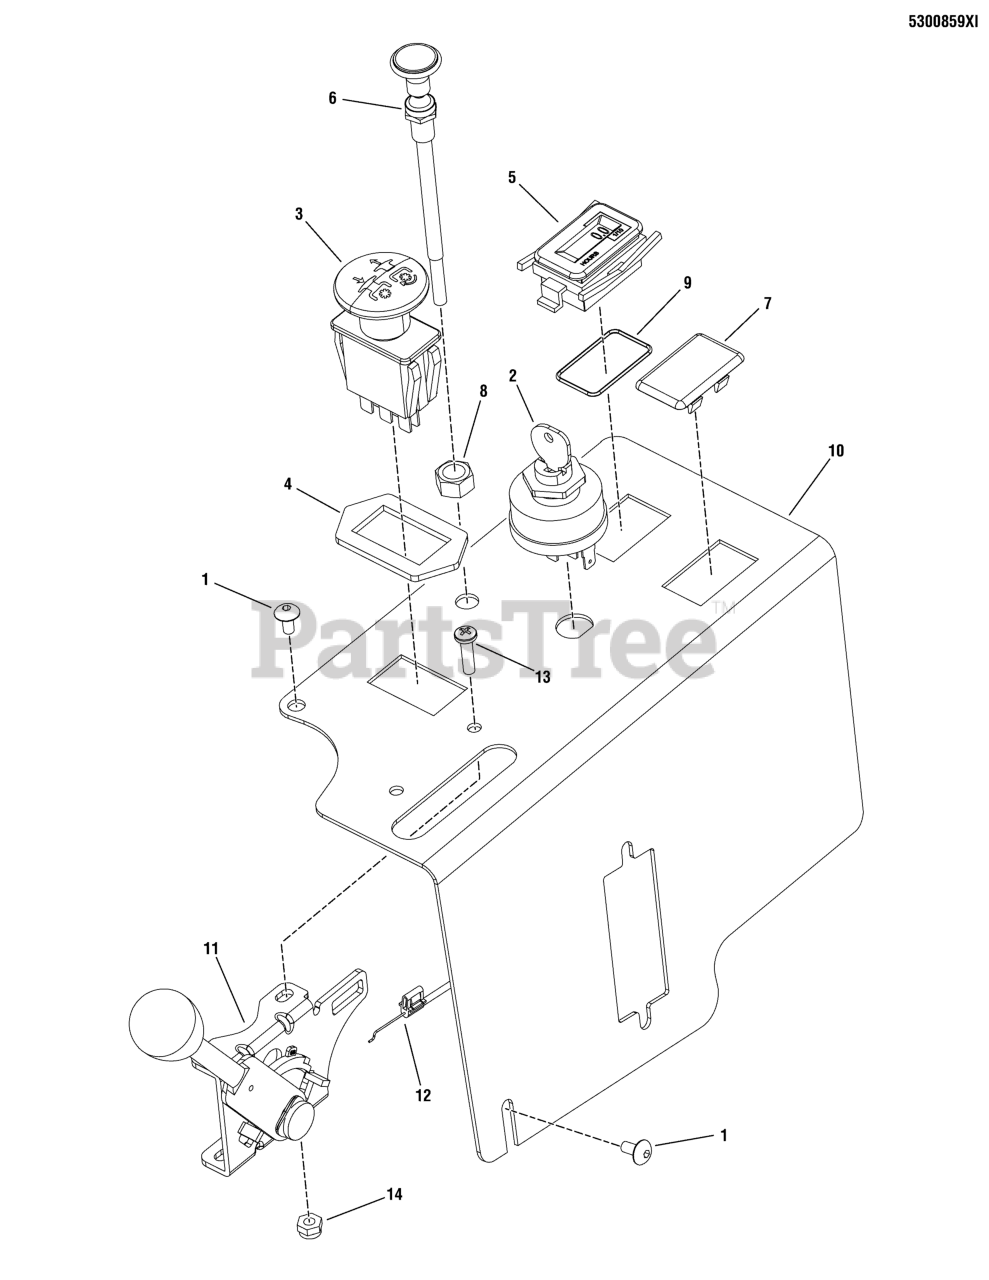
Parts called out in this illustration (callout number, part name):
1	SCREW, ALLEN HEAD 1/4-20X.500 ZINC PHOS
2	SWITCH, IGNITION, 6 POST
3	SWITCH, BLADE ENGAGEMENT
4	RING, SWITCH RETAINER
5	* HOUR METER, ASSEMBLY
5	HOUR METER
6	CABLE, CHOKE CONTROL, 47
6	CABLE, CHOKE CONTROL, 43.5"
7	PLUG, .820X1.44 HOLE, BLACK PLASTIC
8	NUT, 3/8-24 HEX
9	O-RING, 7/8 ID X 1/16 W
10	PLATE, CONTROL PANEL, SNP - BLK
10	PLATE, CONTROL PANEL, S200XT
11	LEVER, THROTTLE CONTROL, HEAVY-DUTY
12	CABLE, THROTTLE, 42"
13	SCREW, #10-24 X 3/4 ROUND PHILLIPS
14	NUT, #10-24 HEX NYLON LOCK
